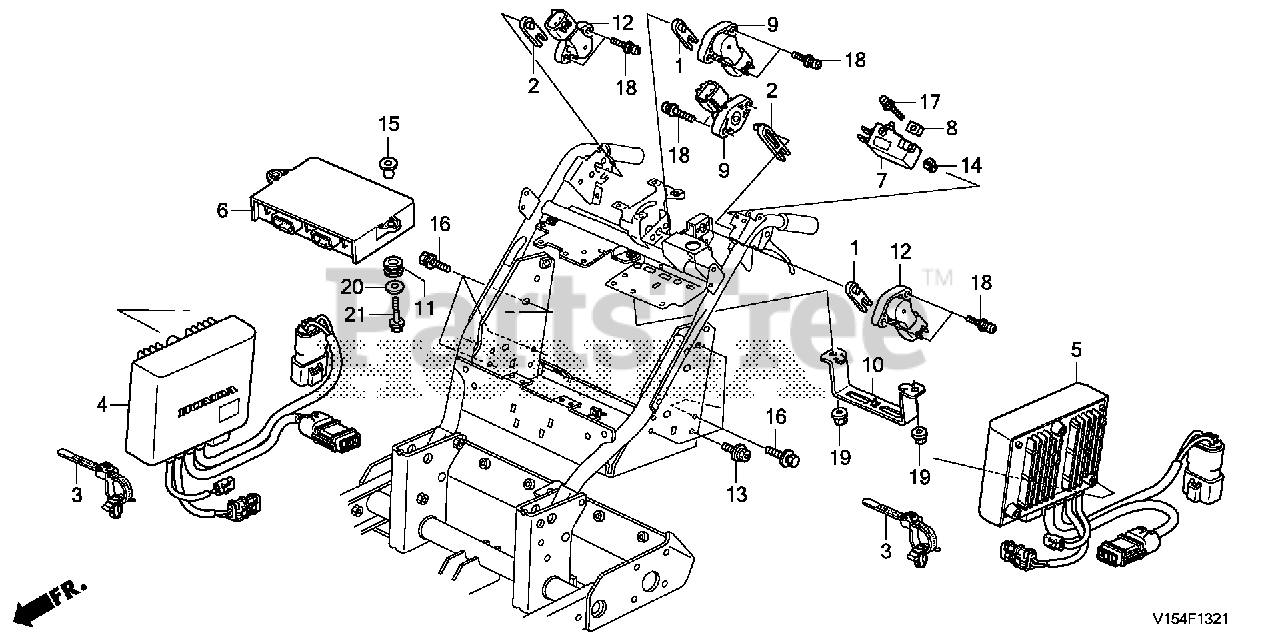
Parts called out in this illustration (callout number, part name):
1	ARM, CHANGE LEVER
2	ARM, TURN LEVER
3	BAND, WIRE HARNESS
4	CONTROL UNIT, R.
5	CONTROL UNIT, L.
6	CONTROL UNIT, ELECTRONIC
7	SWITCH ASSY., FR. STOP (COO)
7	SWITCH ASSY., FR. STOP (OMRON)
8	COLLAR, STOP SWITCH
9	SENSOR ASSY., ANGLE
10	BRACKET, FUSE
11	GROMMET, RELAY
12	SENSOR ASSY., ANGLE
13	BOLT, GROUND (6X16) (WASHER 12.5MM) (ZN)
14	NUT, SPECIAL (4MM)
15	COLLAR, MODULE IGNITION CONTROL CASE (CDI)
16	BOLT-WASHER (6X20)
17	SCREW-WASHER (4X25)
18	SCREW-WASHER (5X18) (NOT AVAILABLE)
19	NUT, FLANGE (6MM)
20	WASHER, PLAIN (6MM)
21	BOLT, FLANGE (6X22)
